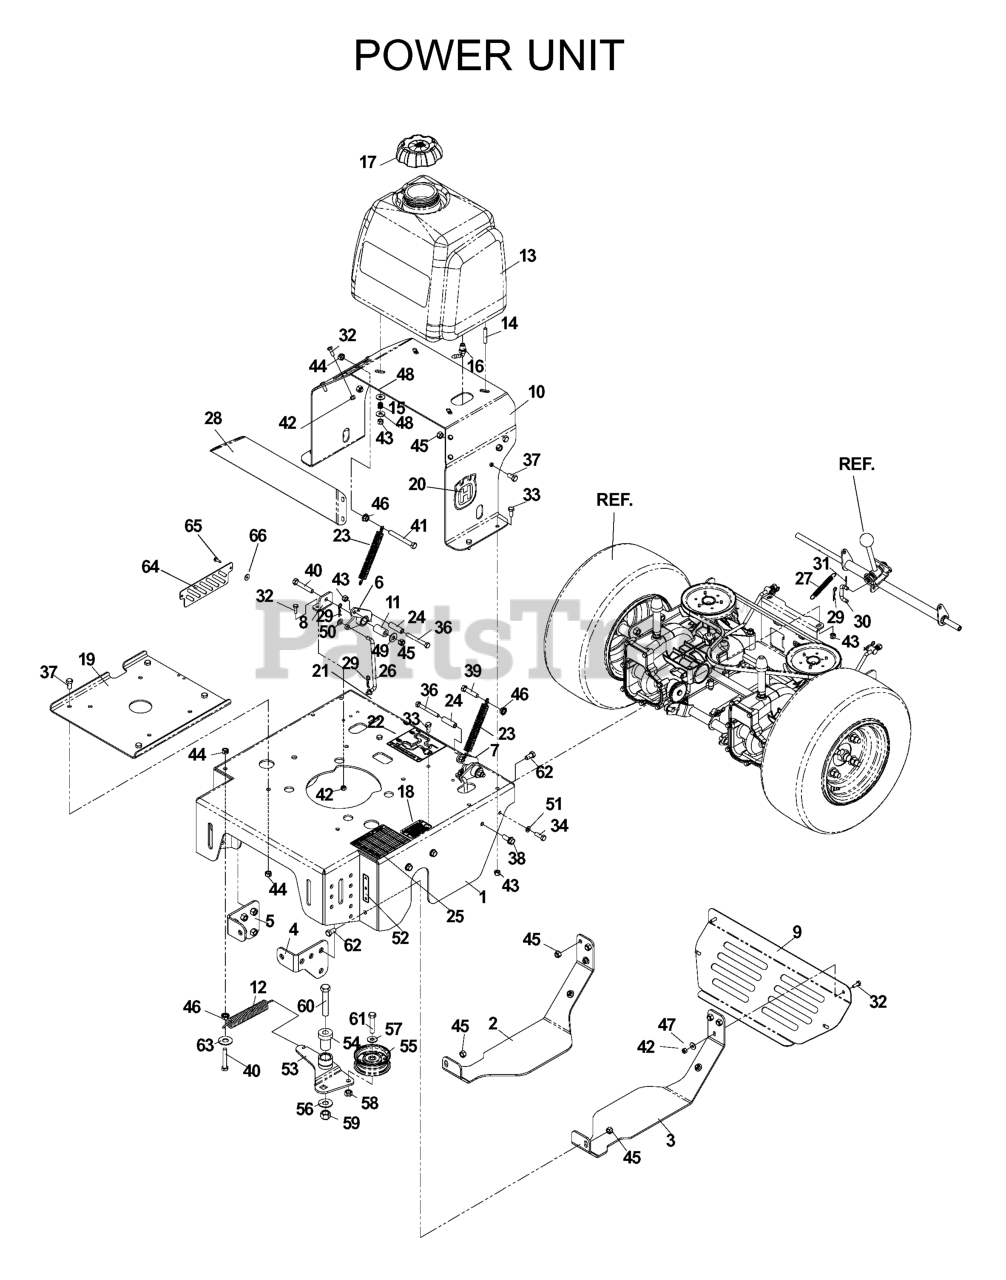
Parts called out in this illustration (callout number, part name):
1	REAR DECK W/ DECALS
2	SKID PLATE, RT
3	SKID PLATE, LT
4	NUT PLATE, LT
5	NUT PLATE, RT
6	BELLCRANK, RT, ETS
7	BELLCRANK, LT, ETS
8	CONTROL BRAKE
9	REAR GUARD
10	TANK SUPPORT
11	BUSHING, SLEEVE
14	STUD, 5/16C
16	HOSE BARB 90 DEGREE
17	FUEL CAP ANTI-SPLASH
18	DECAL, PROP. 65
19	ENGINE PLATE, ORANGE
20	DECAL, CROWN H
21	DECAL, BELT DRIVE
22	DECAL, BYPASS/BRAKE
23	SPRING-TRANS
25	DECAL, HEIGHT
26	CONTROL LINKAGE
28	PANEL, ORANGE
29	HAIRPIN #2
30	BRAKE ENGAGE LINKAGE
31	COTTER PIN 3/32 X 3/4
32	HCS 1/4C X 3/4 HCS
33	HCS 5/16C X 3/4
34	HCS 5/16C X 1
36	HCS 5/16C X 2-3/4
37	SCREW 3/8C X 3/4 HEX CAP
38	4CS 3/8C X 1 SERRATED HEAD
39	HCS 3/8C X 2 1/2
40	HCS 3/8C X 2 1/4
41	HCS 3/8C X 3 1/2
42	NUT.1/4-20.HEX.NYLOC.ZD
43	NUT 5/16 NYLOC
44	NUT 3/8C CENTERBLOCK
45	NUT 3/8-16 NYLOC
46	NUT 3/8C WHIZ
47	WASHER 1/4 FLAT
48	WASHER 5/16 FLAT
49	WASHER 3/8 FLAT
50	FLAT WASHER 5/16 SAE
51	WASHER.LOCK.HVY.HLCL.SPR.5/16
52	DECAL, POSITION
53	IDLER ARM WELDMENT
54	IDLER SPINDLE
55	IDLER PULLEY
56	WASHER 1/2 FLAT
57	WASHER 5/16 FLAT
58	NUT 3/8C CENTERBLOCK
59	NUT 1/2-13 HEX NYLOC ZD
60	HCS 1/2C X 2 3/4
61	HCS 3/8-16 X 1 3/4 GR5
62	HCS 3/8-16X1.GRD.5.ZD
63	WASHER 1/2" FLAT
65	SCREW #10 X 1/2 SELF TAPPING
66	WASHER #10
539109104	LOWER HARNESS
539109867	DOUBLE TUBE CLAMP
539976856	TIE, PLASTIC
